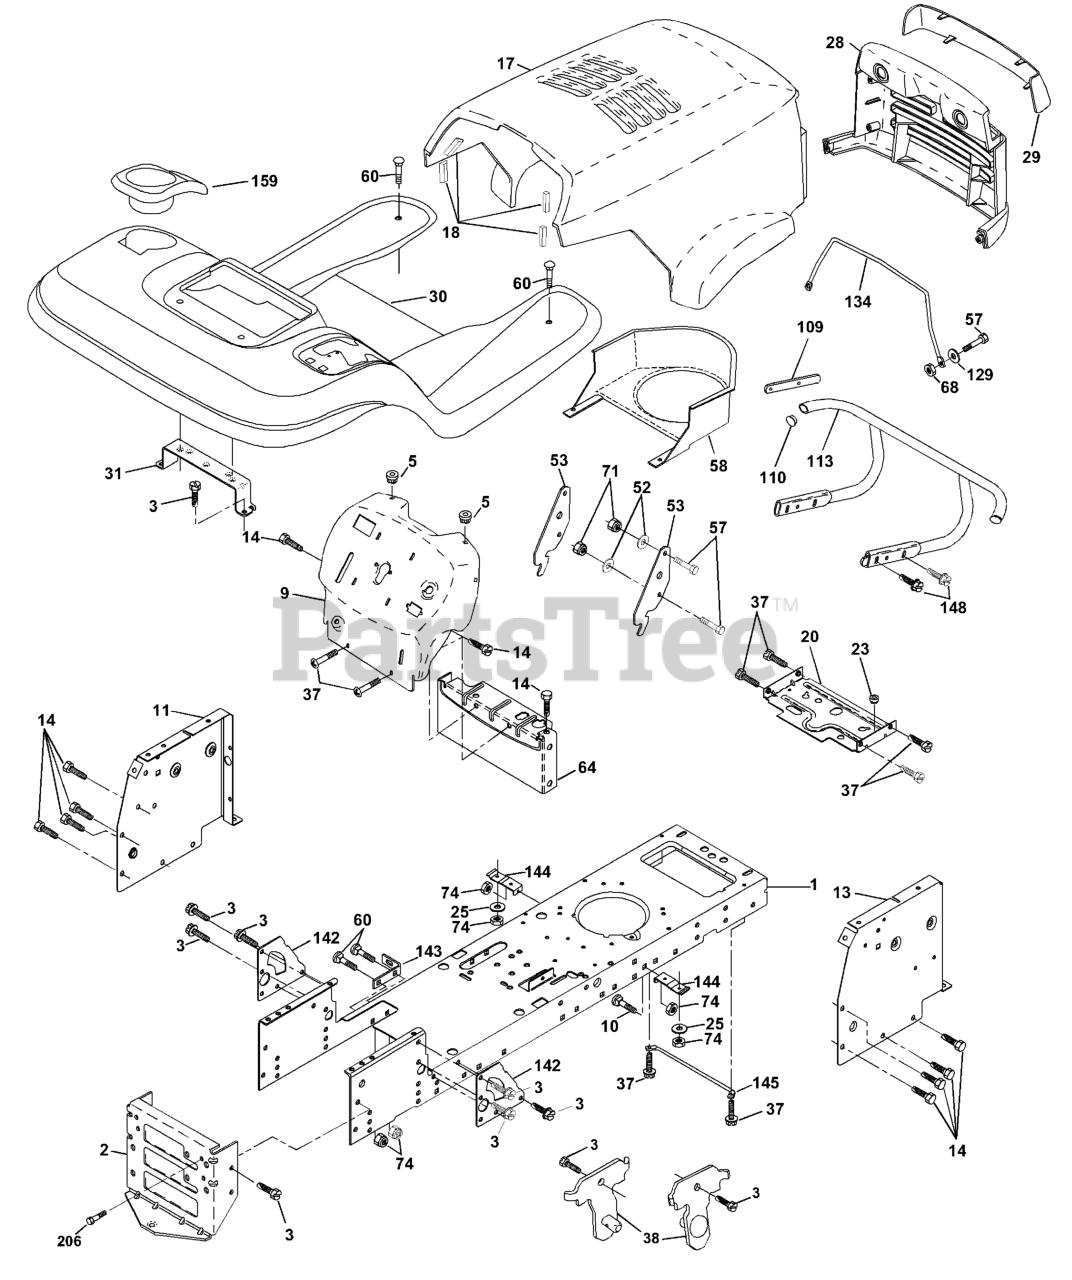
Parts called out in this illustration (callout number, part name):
2	DRAWBAR
3	SCREW 3/8-16X3/4
5	BUMPER.RUBBER.HOOD
9	DASH SLKSCR
10	BOLT D
11	PANEL DASH LH
13	PANEL DASH RH
14	SCREW LT
17	HOOD
18	BUMPER HOOD T
20	PLATE MTG
23	BUSHING.SNAP.NYL.BLK.
25	WASHER
28	GRILL
29	LENS
30	FENDER FOOTREST STLT PNT
31	BRACKET.SUPPORT.FENDER
37	Screw Thdrol 6/16-18 x 1/2 TYT
38	BRACKET
52	WASHER
53	BRACKET PNT PICK OFF LT/PL
57	BOLT
58	AIR DUCT P/L/LT
60	Bolt Rdhd Sqnk 3/8-16unc x 3/4
64	DASH LOWER
68	NUT
71	NUT.CROWNLOCK.1/4
109	BUMPER BRACKET
110	PLUG PLASTIC
113	BUMPER ASM.
129	WASHER
134	ROD SUPPORT HOOD LT/PL HUS.
142	PLATE
143	BRACKET, SWAY BAR
144	BRACKET FOOTREST
145	ROD PIVOT CHASSIS/HOOD
148	SCREW.3/8-16
159	CUPHOLDER
206	SHOULDER BOLT 5/16-18TT
